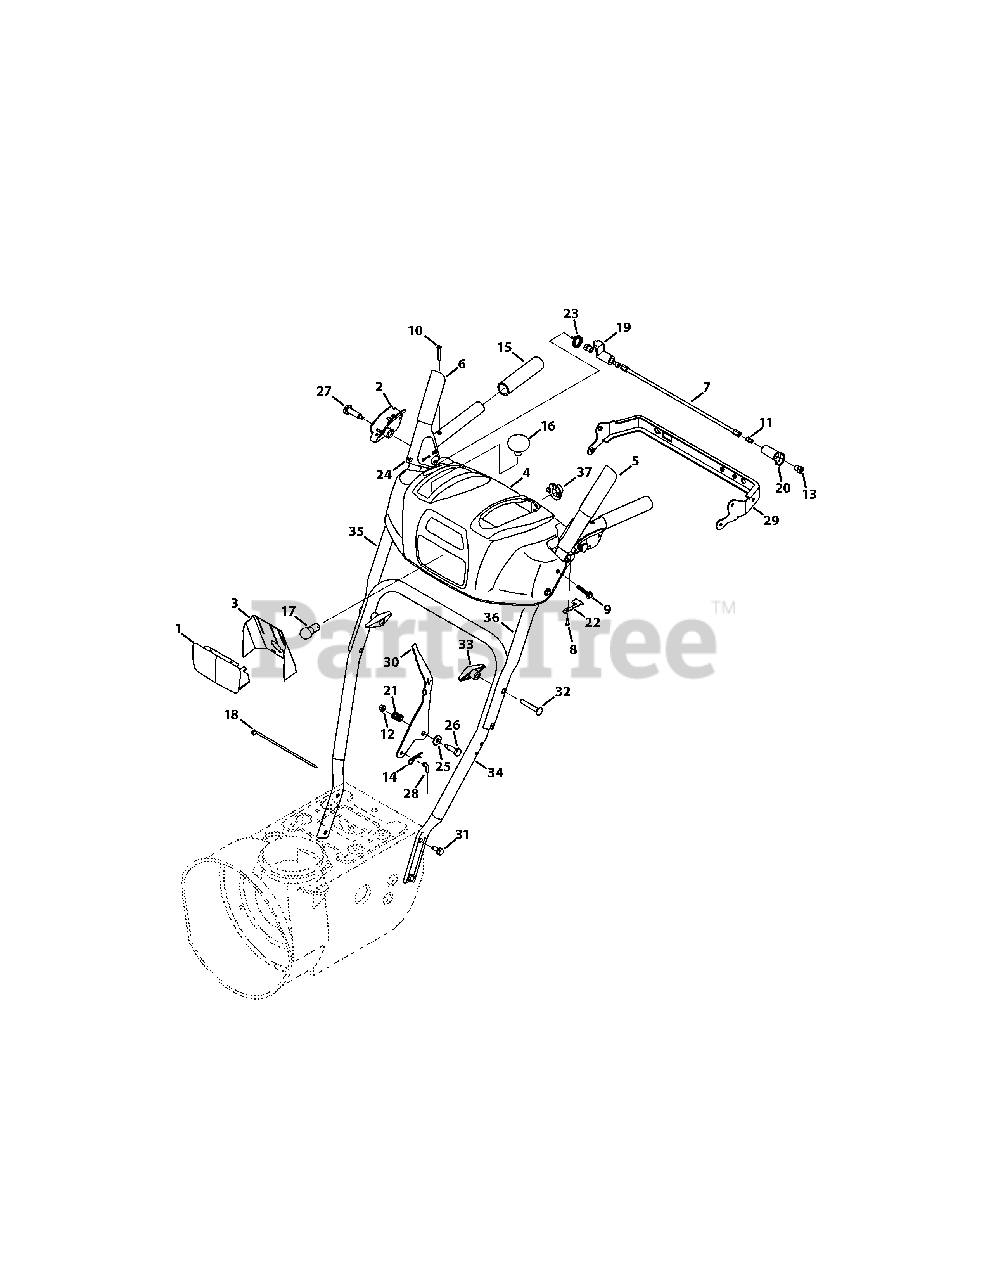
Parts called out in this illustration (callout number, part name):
2	Handle Clutch Lock - RH
2	Handle Clutch Lock - LH
3	Lens Reflector Label
4	T-Style Panel Ass’y, (inc. Ref. 1 & 3)
5	Handle Engagement Assembly LH
6	Handle Engagement Assembly RH
8	Screw, Plastite, 8-16 x .50
9	Screw, 1/4-20 x 1.625
10	Screw, #10-24 x 1.375
11	Screw, Socket, 1/4-20 x .50
12	Flange Lock Nut, 1/4-20
13	Shoulder Nut, 1/4-20
14	Click Pin
15	Handle Grip
16	Shift Knob
17	Lamp
18	Cable Tie
20	Clutch Lock Cam
21	Compression Spring
22	Clutch Lock Spring
23	Torsion Spring
24	Rubber Bumper
25	Flat Washer, .385 x .87 x .06
26	Shoulder Screw, .374 x 1.05
27	Shoulder Screw, 1/4-20 x 1.345
28	Speed Selector Cable
29	Panel Bracket
30	Shift Lever
31	Screw, 5/16-18 x .750
32	Carriage Screw, 5/16-18 x 2.25
34	Lower Handle
35	Upper Handle RH
36	Upper Handle LH
37	Light Socket
